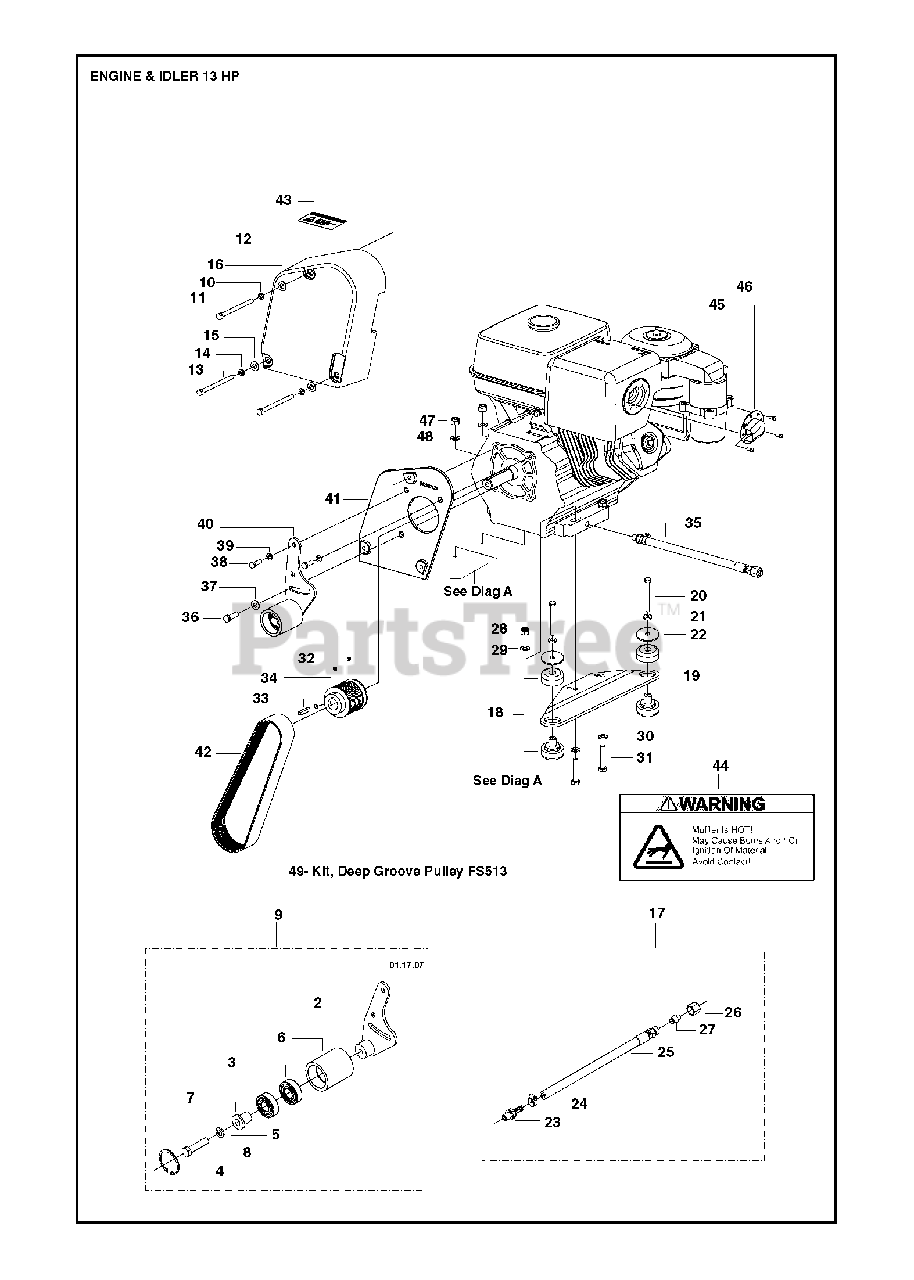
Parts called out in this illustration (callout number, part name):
9	IDLER SHEAVE ASSEMBLY
10	SPRING WASHER
14	SPRING WASHER
15	WASHER
16	WASHER
24	CLAMP, HOSE, MAH-4 FUEL LINE
28	HEXAGON LOCKING NUT
29	WASHER
30	WASHER
39	SPRING WASHER
40	IDLER SHEAVE ASSEMBLY
46	SCREW CCRPANT
47	HEXAGON LOCKING NUT
48	WASHER
